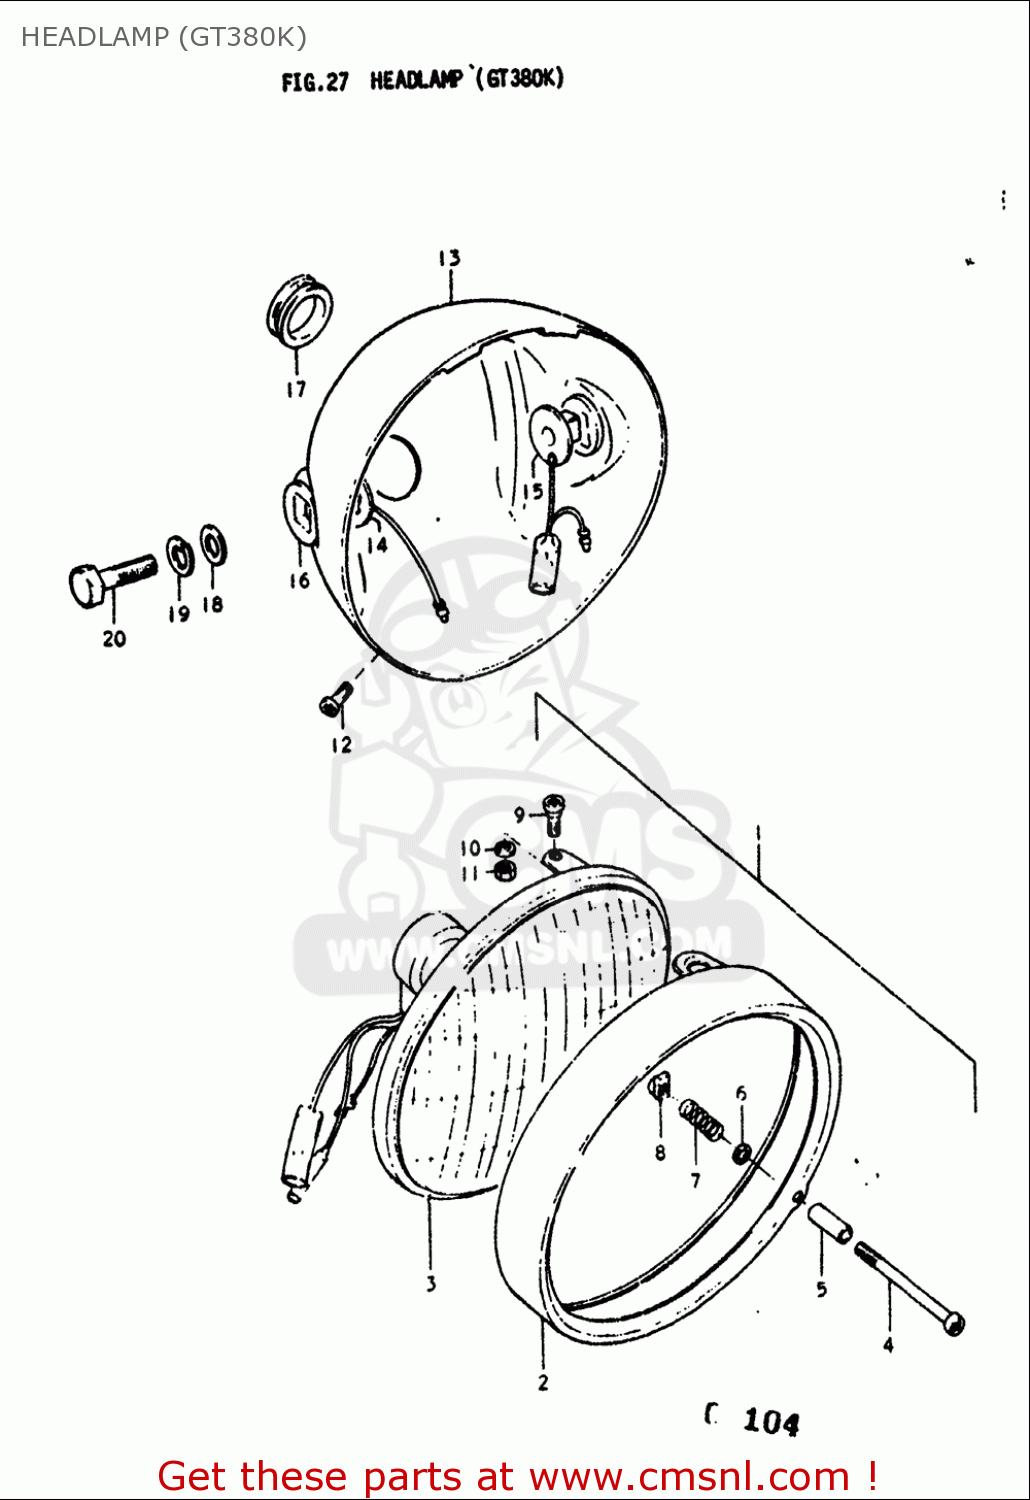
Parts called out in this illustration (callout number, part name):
4	SCREW
6	WASHER
8	NUT
9	H/LAMP LENS UNIT FITING SCRE
10	WASHER,LOCK
11	NUT
12	SCREW
17	GROMMET,HEADLAMP HOUSING
18	WASHER
19	WASHER,LOCK
20	BOLT
